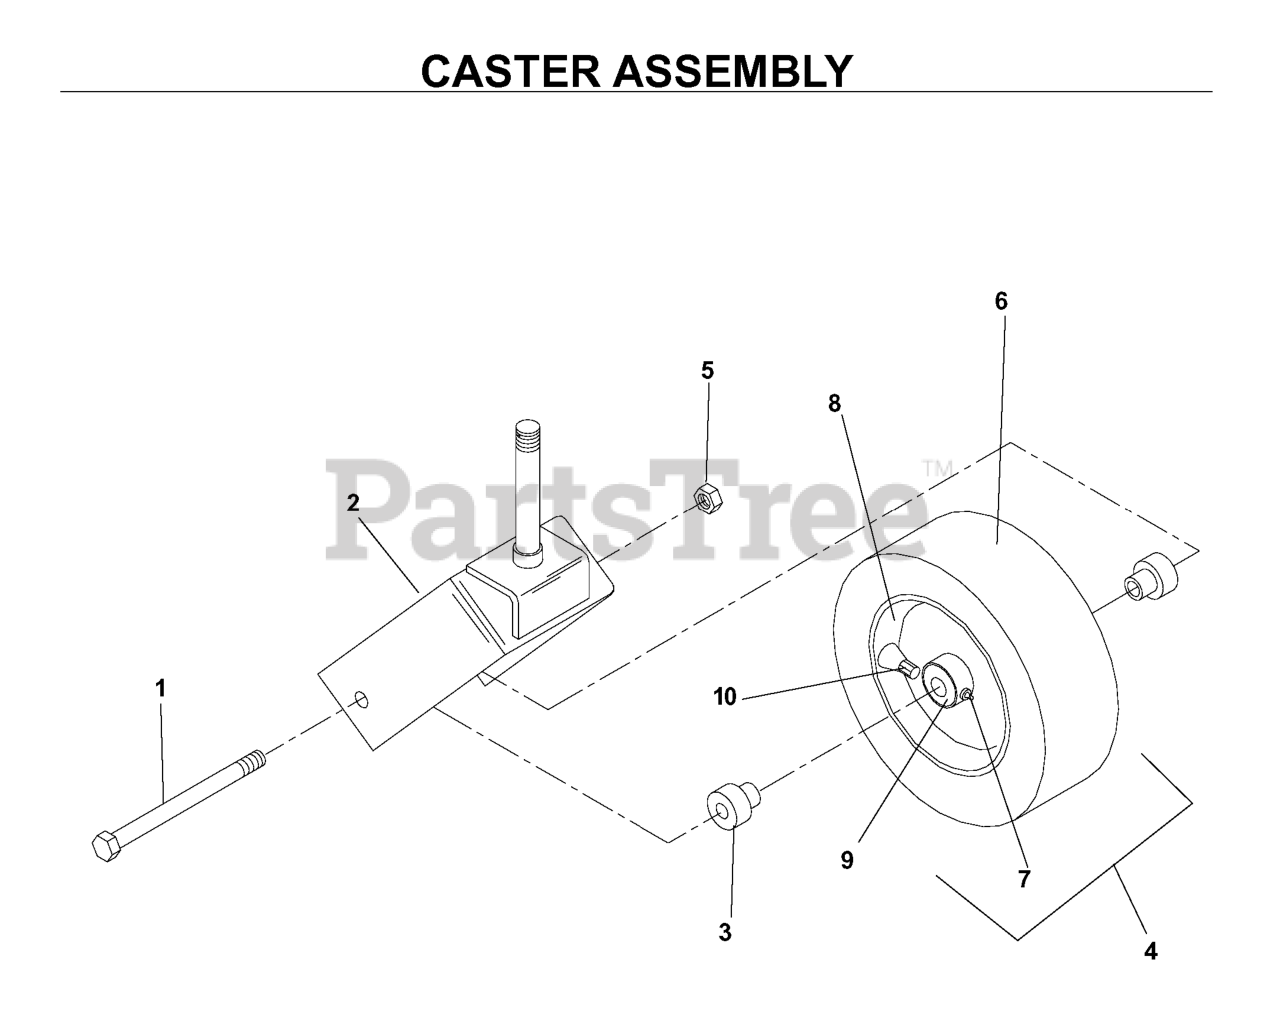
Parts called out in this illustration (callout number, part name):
1	HEX SCREW 1/2-13 X 9.5 GR5
2	CASTOR YOKE ORANGE
3	AXLE SPACER
4	FRONT TIRE ASSY
5	NUT 1/2-13 HEX NYLOC ZD
6	TIRE - SMOOTH 13X6.50-6
7	ZERK
10	VALVE STEM TR-412
539105525	TAPERED BEARING W/RACE
